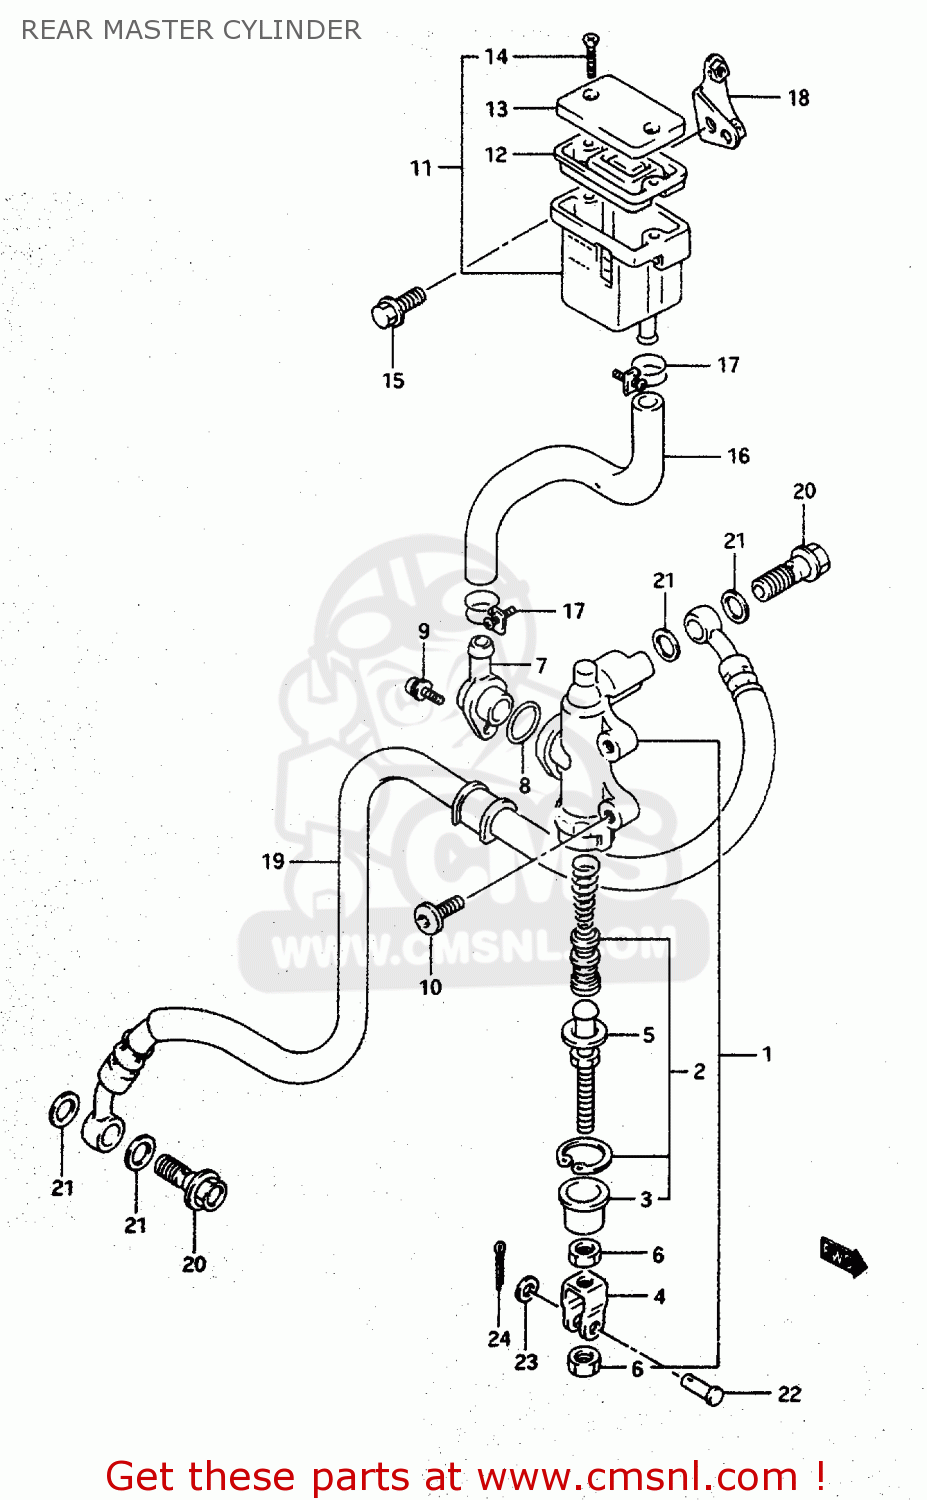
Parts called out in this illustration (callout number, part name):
1	CYLINDER ASSY,RR MASTER
2	PISTON/CUP SET
3	BOOT
4	YOKE
5	ROD,PUSH
6	NUT
7	CONNECTOR
8	O RING
9	SCREW
10	BOLT 8X20
11	TANK ASSY,RESERVOIR
12	DIAPHRAGM
13	CAP
14	SCREW
15	BOLT
16	HOSE,RESERVOIR TANK
17	CLIP
18	PLATE COMP,RESERVOIR T
19	HOSE,RR BRAKE
20	BOLT UNION
21	WASHER(10X15X1.5)
22	PIN
23	WASHER
24	PIN
